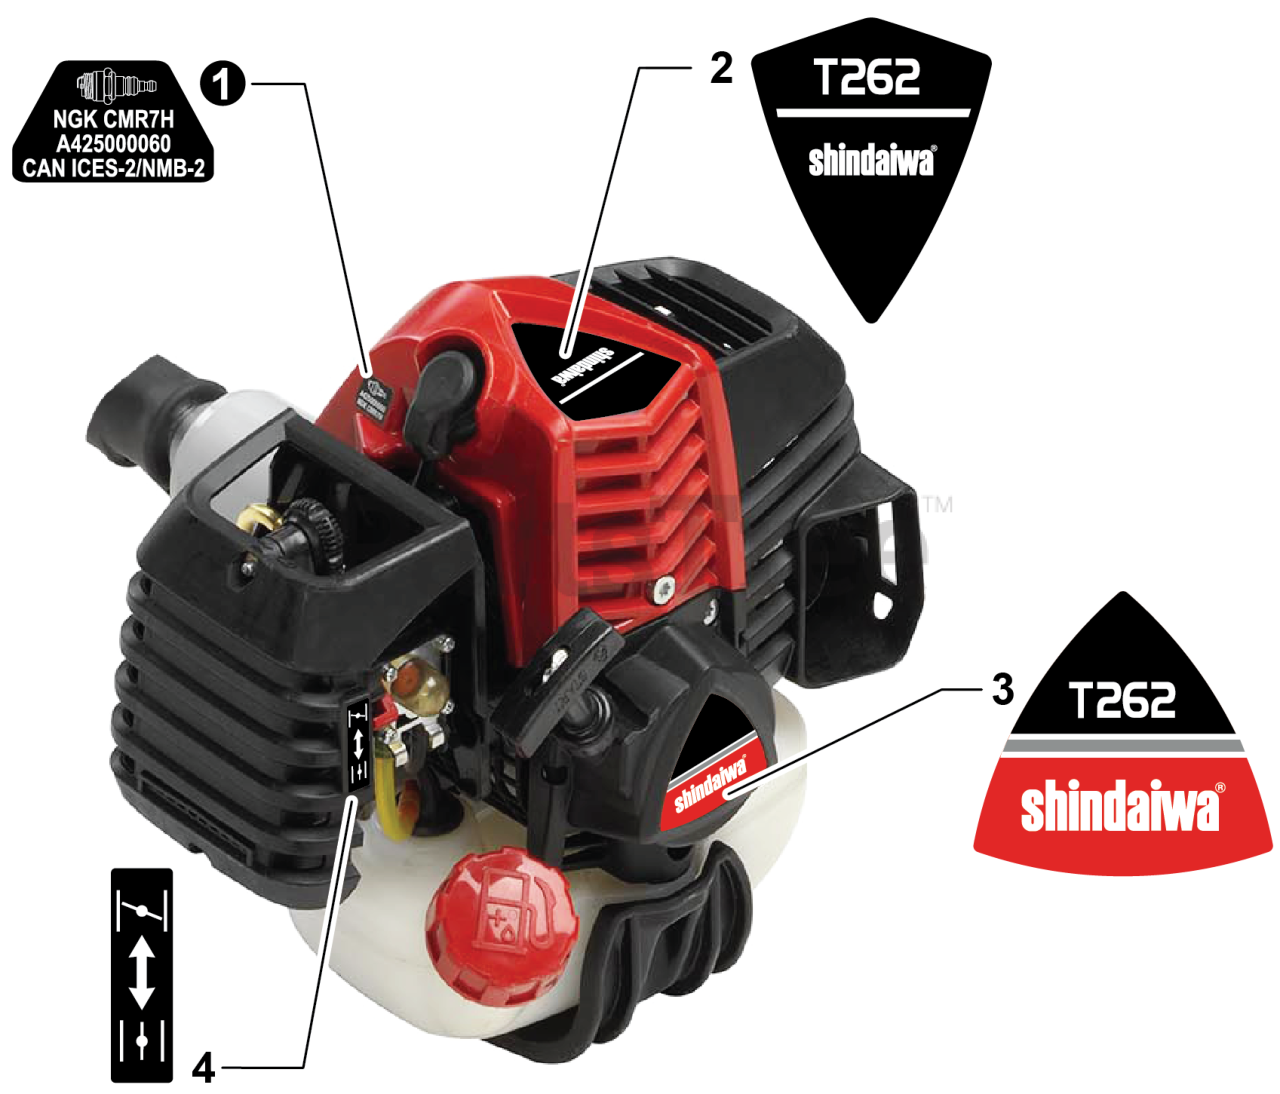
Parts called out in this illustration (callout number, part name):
1	LABEL - SPARK PLUG - CMR7H
2	LABEL - MODEL T262
3	LABEL - RECOIL STARTER
4	LABEL - CHOKE
